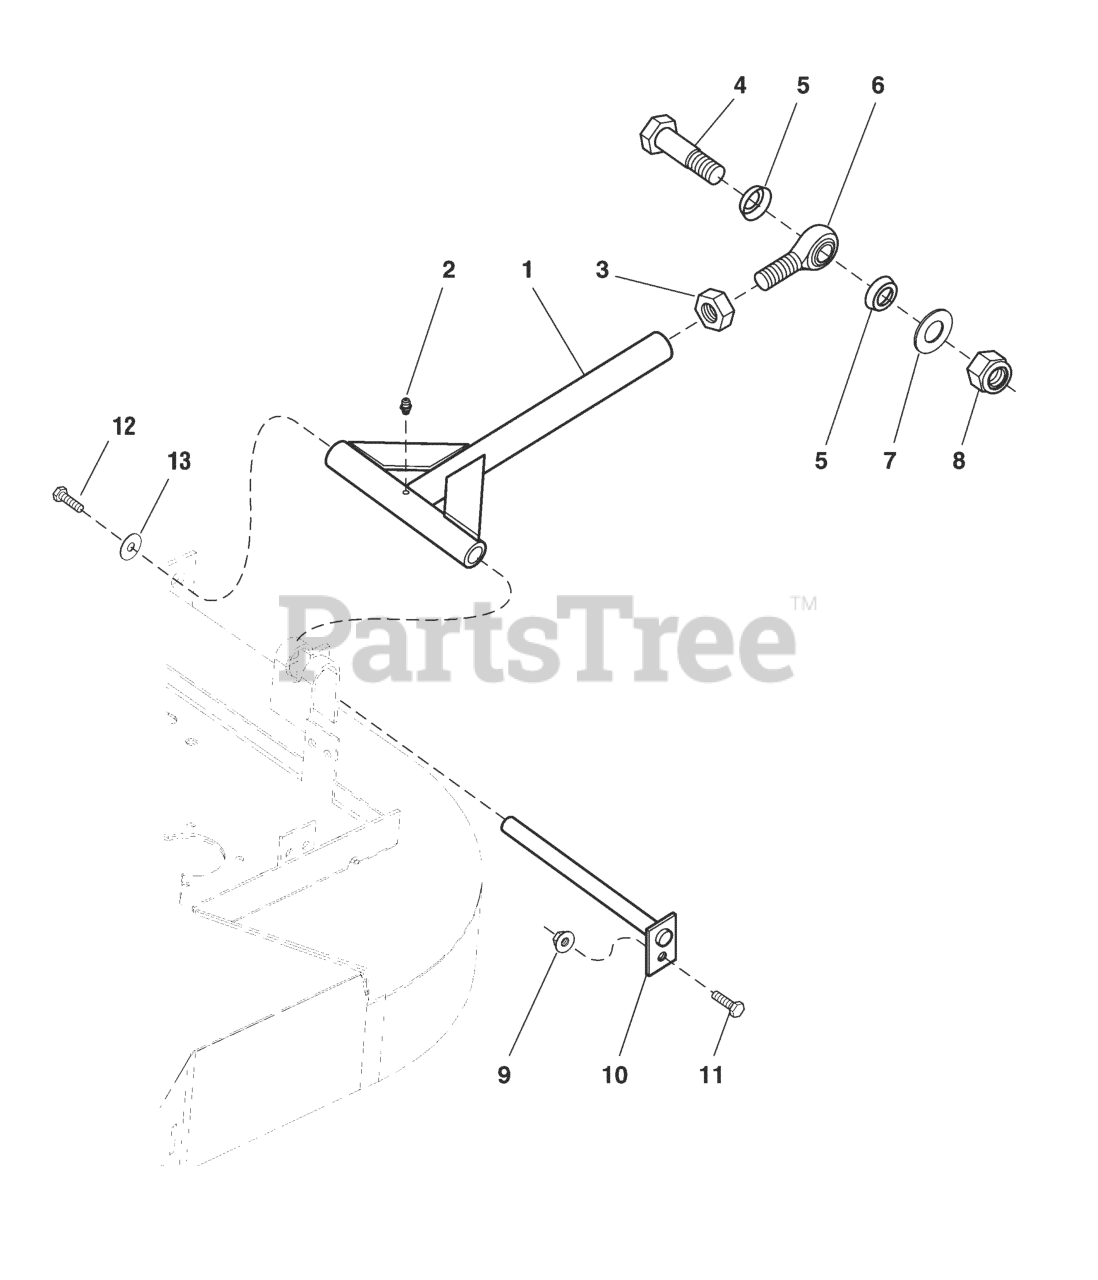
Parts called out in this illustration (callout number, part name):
1	ASSM, DECK PUSHER BAR
2	GREASE FITTING
3	NUT, 3/4-16 Hex Jam
4	BOLT, 3/4-16 x 3
5	ROD END SEAL
6	BALL JOINT, 3/4-16 Male
7	WASHER, 3/4 SAE
8	NUT, 3/4-16 Hex Nylon Lock
9	NUT, 5/16-18 HEX SERRATED FLANGE (LARGE)
11	BOLT, 5/16-18 X 1 GD5 YZ
12	BOLT, 3/8-16 X 1" GD5 CZ
13	WASHER, .390 X 1.50 X .109 YZ
